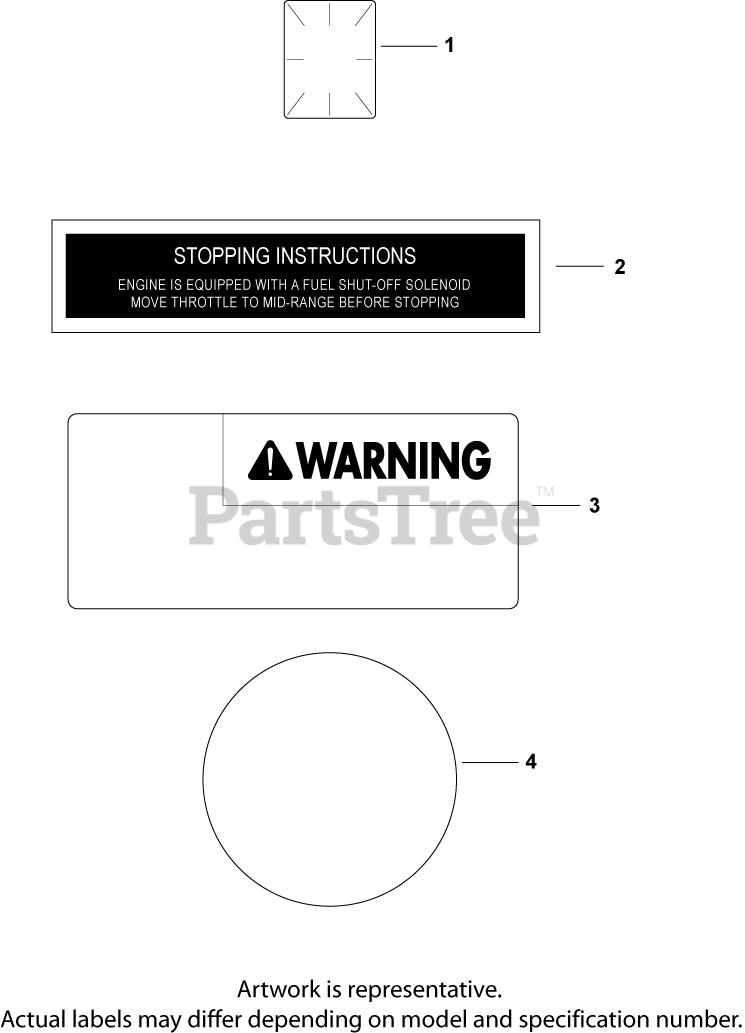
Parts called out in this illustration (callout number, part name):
1	DECAL, CLEAR LAMINATE USE 25 113 70-S
2	DECAL, STOPPING INSTRUCTION
3	DECAL, WARNING
4	DECAL, GRASS SCREEN USE 24 113 499-S
